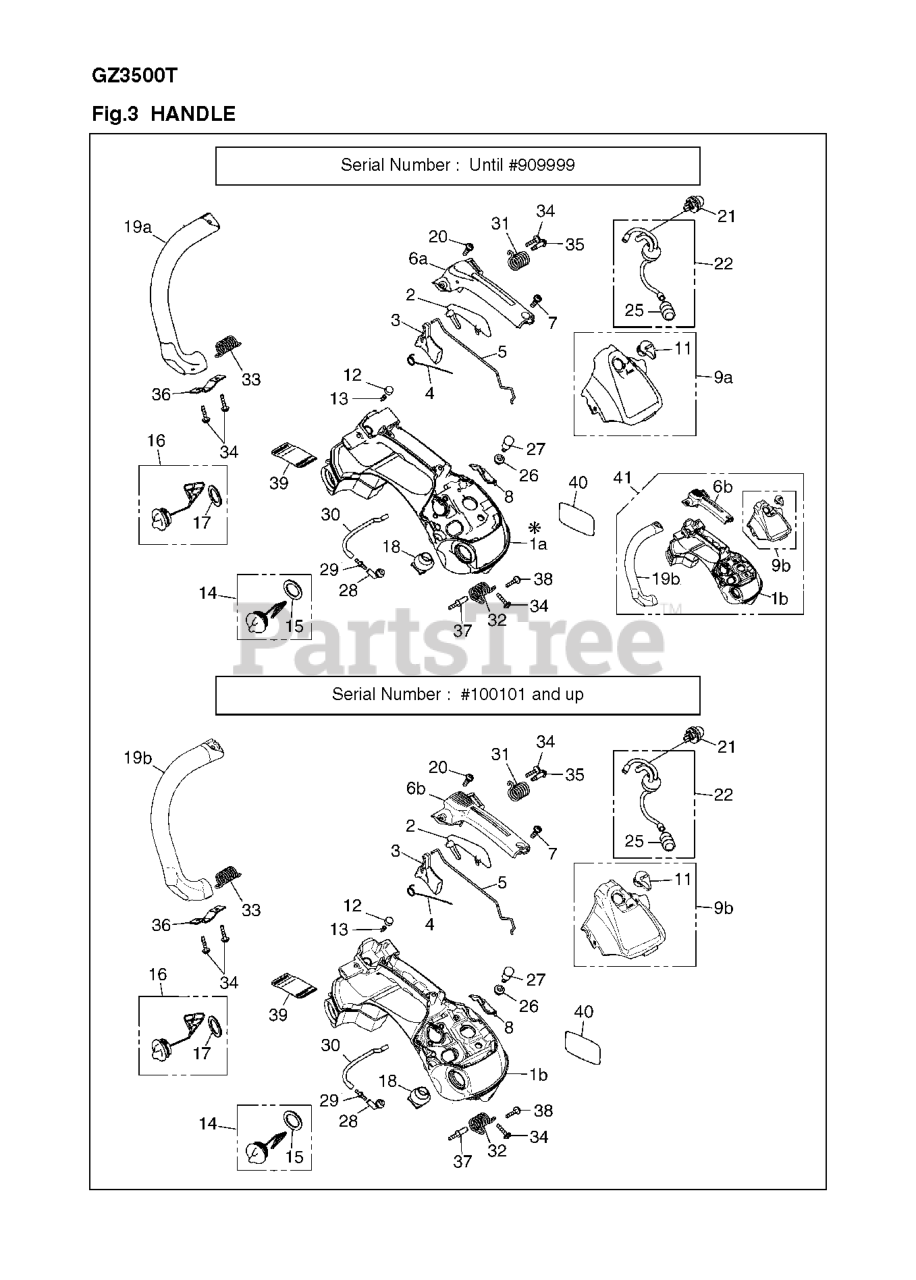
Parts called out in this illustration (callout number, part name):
1	%HANDLE, COMP
1	HANDLE, COMP
2	ARM (RPLS 335633350-335633352)
3	LEVER, TH
6	RP_COVER, GRIP
6	COVER, GRIP
8	BRACKET, KNOB
9	COVER COMP
9	COVER, COMP
12	BREATHER SEAL
13	AIR CONTROL BREATHER
14	CAP ASSY
15	GASKET
16	CAP ASSY
17	GASKET
18	PIPE, AIR
19	RP_L, HANDLE
19	FRONT HANDLE
21	PRIMARY BTN
22	PIPE ASSY
26	PIPE ASSY
27	BREATHER
30	PIPE
31	SPRING, FRONT
32	SPRING, PTO
33	DAMPER, MAG
37	BOLT
38	SCREW (RPLS 267132210)
41	HANDLE SET
